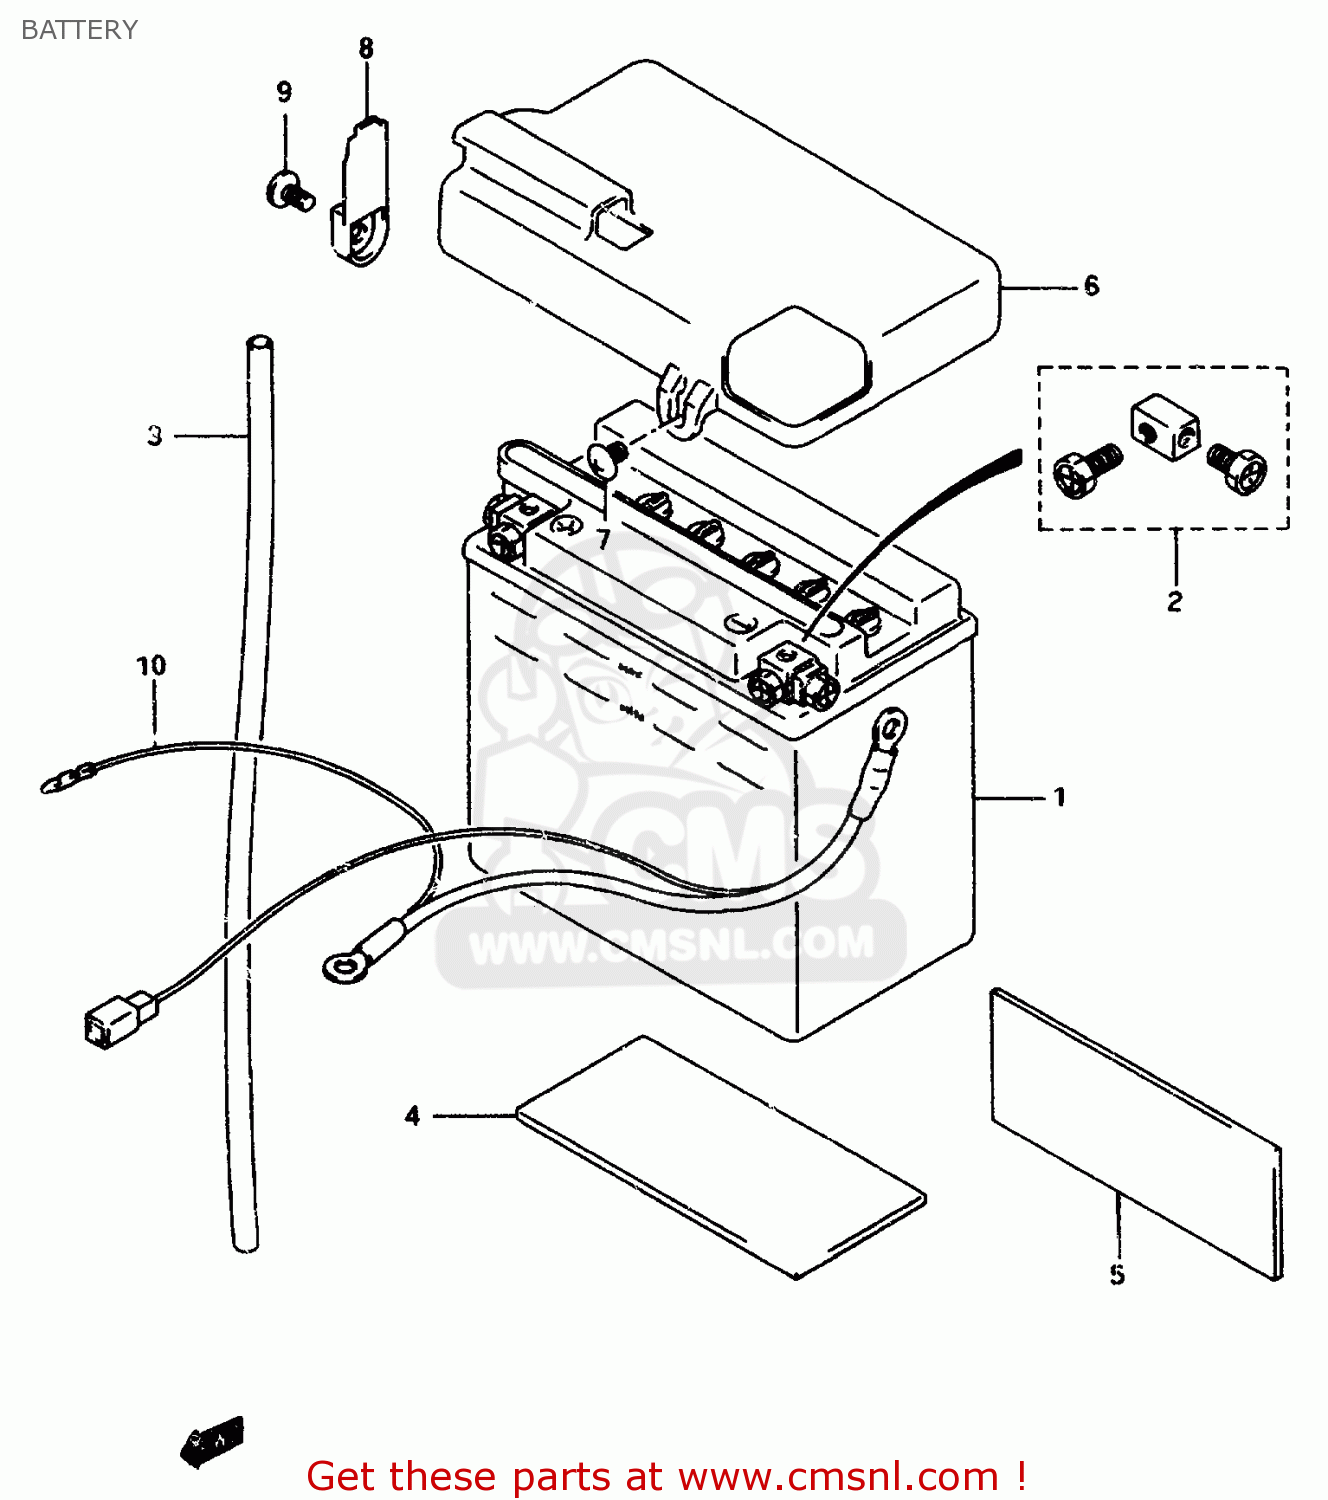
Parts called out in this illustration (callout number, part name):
1	BATTERY ASSY (12V)
2	BOLT SET,BATTERY TERMINAL
3	HOSE,BATTERY EXHAUST(L:780)
4	PROTECTOR(170X95X3.0)
5	PROTECTOR(80X80X2)
6	COVER,BATTERY UPR
7	SCREW
8	COVER,BATTERY TERMINAL
9	SCREW
10	WIRE,BATTERY MINUS LEAD
